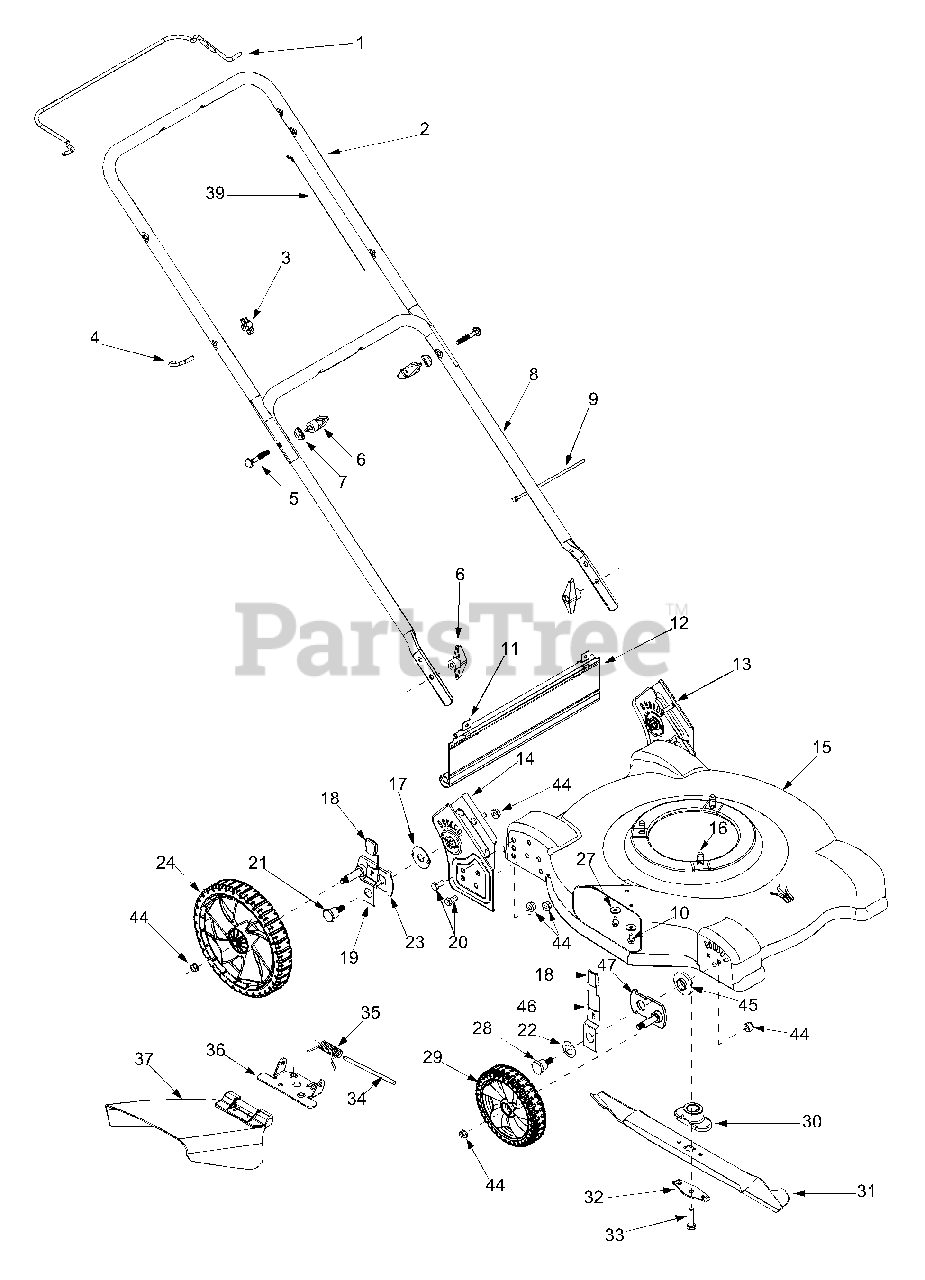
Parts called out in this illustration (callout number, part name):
3	Wing Nut
4	Eye Bolt
5	Carriage Bolt 5/16-18 x 2.0
6	Wing Nut
7	Shoulder Washer.320 ID x.93 OD
9	Cable Tie
10	TT Screw 1/4-20 x 0.5"
11	Hinge Clip
12	Trail Shield
16	TT Screw 3/8-16 x 1.0
17	Thrust Bearing
18	Height Adjuster Knob
19	Lever Assembly
20	Hex Cap Screw 3/8-16 x.75
21	Shoulder Screw
22	Bell Washer.760 ID x 1.25 OD
23	Rear Pivot Arm Assembly - RH
24	Rear Wheel 12 x 1.8
27	Bell Washer.265 ID x.75 OD
28	Shoulder Screw
29	Front Wheel 7 x 1.8
30	Blade Adapter
31	Standard Blade 22"
32	Blade Bell Support
33	Hex Cap Screw 3/8-24x 1.5
34	Hinge Pin
35	Torsion Spring
36	Deflector Chute Adapter
37	Hinged Chute Deflector
39	Blade Control Cable - 37.25" Lg.
44	Lock Nut 3/8-16
45	Height Adjuster Bearing
46	Lever Assembly
47	Pivot Arm
